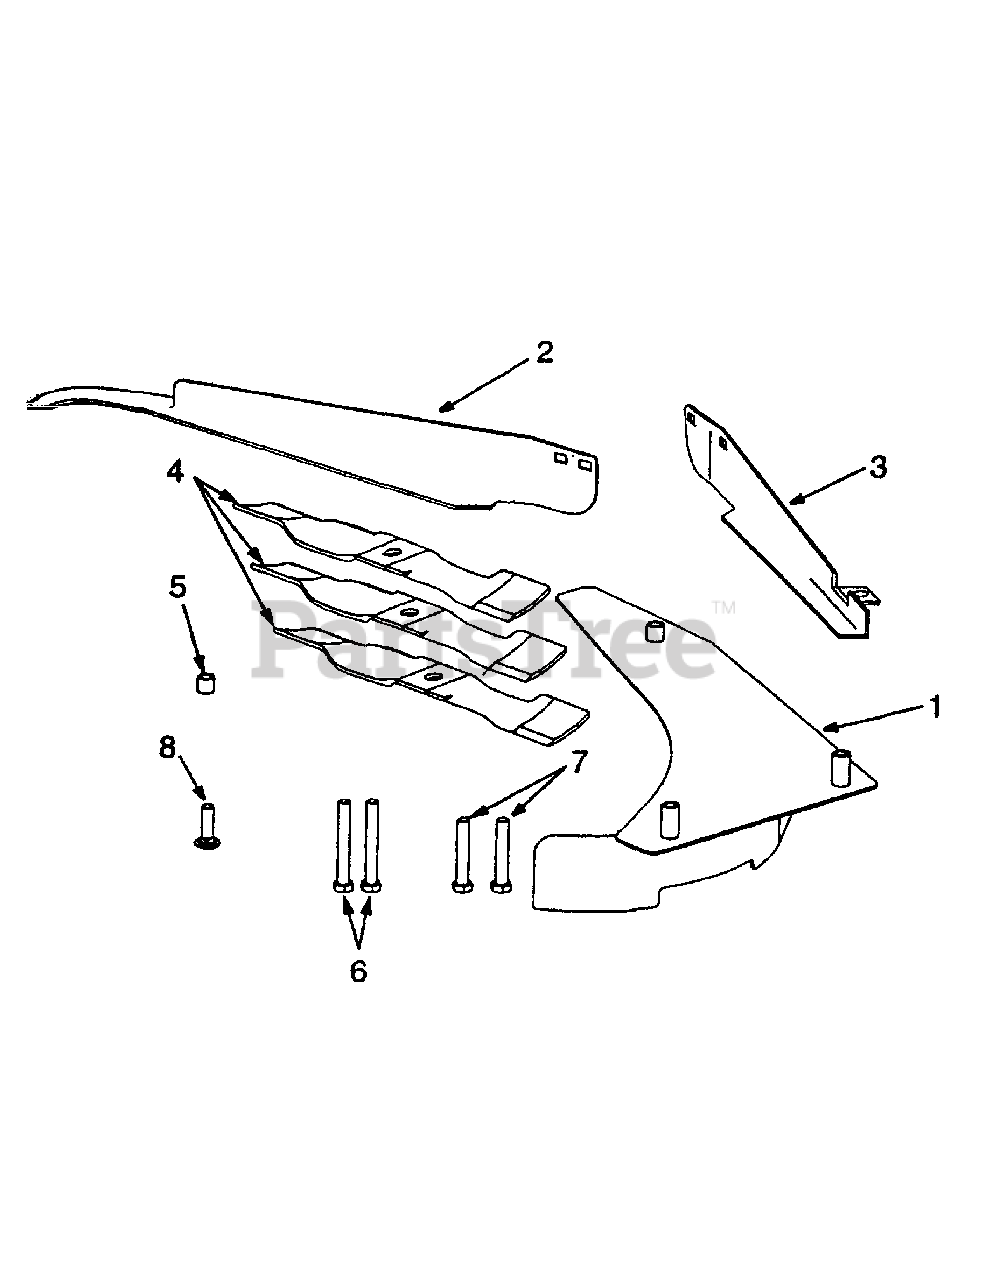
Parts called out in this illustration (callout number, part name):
1	Baffle Ass'y, 48" Mulching
2	Baffle, LH 48"
3	Baffle, RH 48"
4	Blade, Mulching, 16.5 Lg
5	Spacer, .39 ID x .630 OD x 1.1 LG.
6	Screw, Hex Cap, 3/8-16 x 2.25 GR5
7	Screw, Hex Cap, 3/8-16 x 1.75
8	Bolt, Carriage, 3/8-16 x .75 GR5
